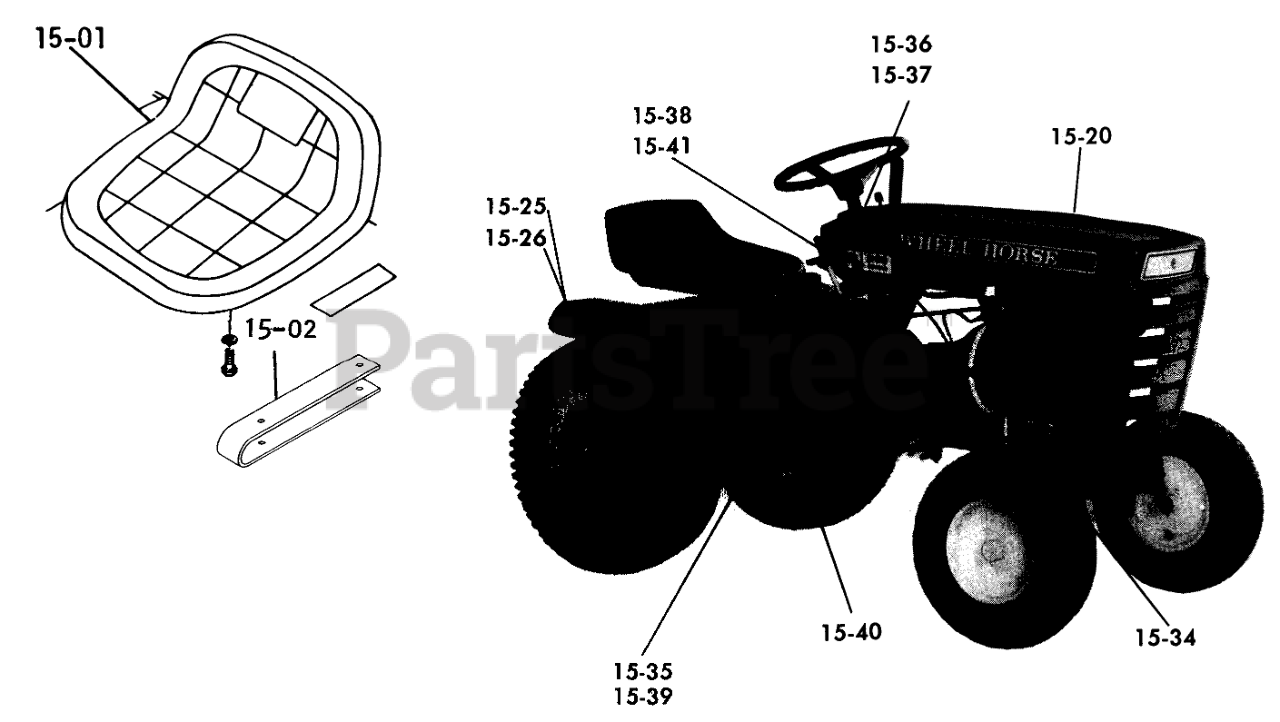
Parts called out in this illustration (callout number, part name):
15-01	Seat, D-160
15-02	Spring
15-20	Decal
15-25	DECAL-WHEEL HORSE
15-26	Reflector
15-34	Decal-Tach-a-matic
15-35	Decal-B-80
15-36	Washer
15-37	Decal-Read Manual
15-38	DECAL-HAND LIFT
15-39	DECAL-4 SPD SHIFT
15-40	Decal-Park Brake
15-41	Decal
